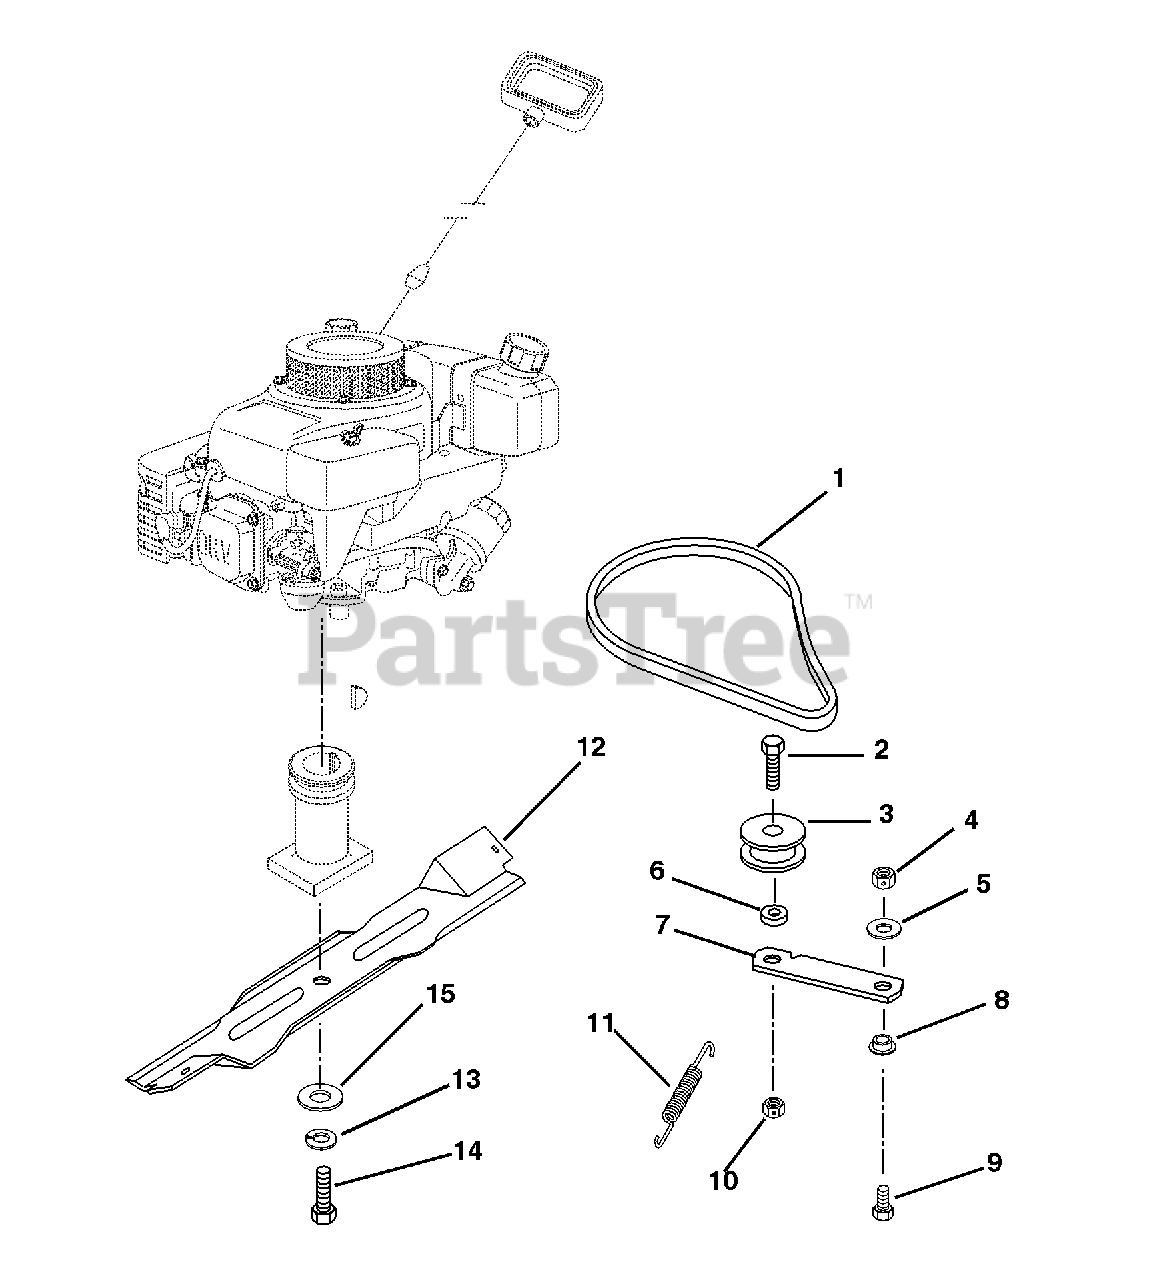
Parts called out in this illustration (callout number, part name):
1	V-BELT, 3L-COGGED
2	@BLT-HEX .44-14X1.25 GR5 YWZC
3	IDLER-FLAT 1.75 X .47
4	@NUT-LK-CTR .31-18 YWZC
5	WSHR-FL-STL .323X.625X.062 YWZ
6	SPACER .52 X .45 X .34
7	IDLER ARM
8	BSHG-FLG .325X.501X.250X1.120
9	@BLT-HEX .31-18X.75 GR5 YWZC
10	@NUT-LK-CTR .44-14 YWZC
11	SG-TENS .043X.44X3.31 WLD 5.8
12	BLADE LM 21 IN
13	@WSHR-LK .38X.094 REG YWZC
14	BLT-HEX .38-24X2.0 YWZC
15	WSHR-FL-STL .390X1.5X.125 YWZC
